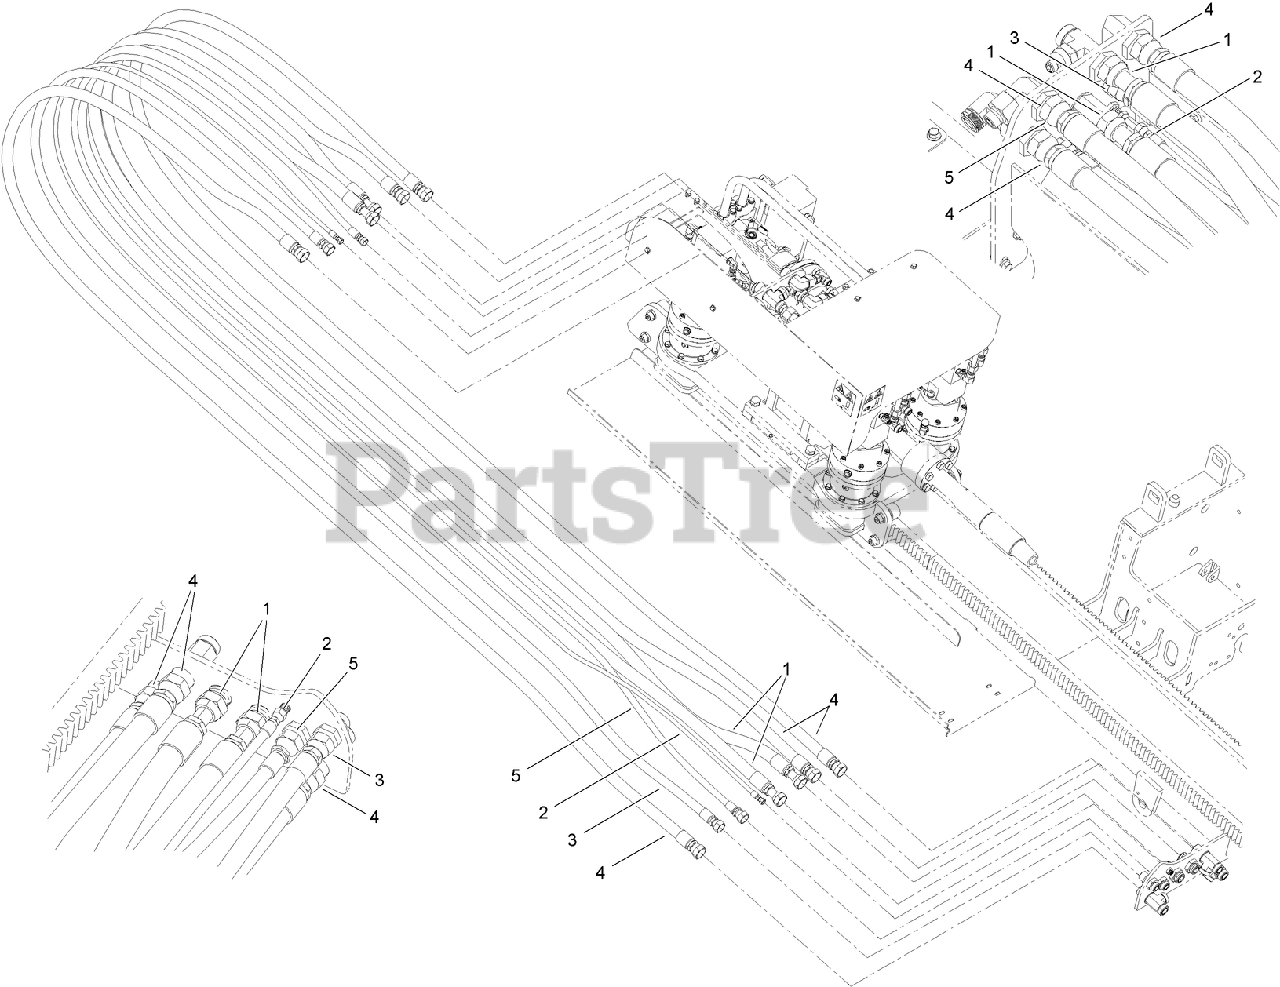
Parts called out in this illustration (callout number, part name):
1	HOSE ASM-HYD
2	HOSE ASM-HYD
3	HOSE ASM-HYD
4	HOSE ASM-HYD
5	HOSE ASM-HYD
